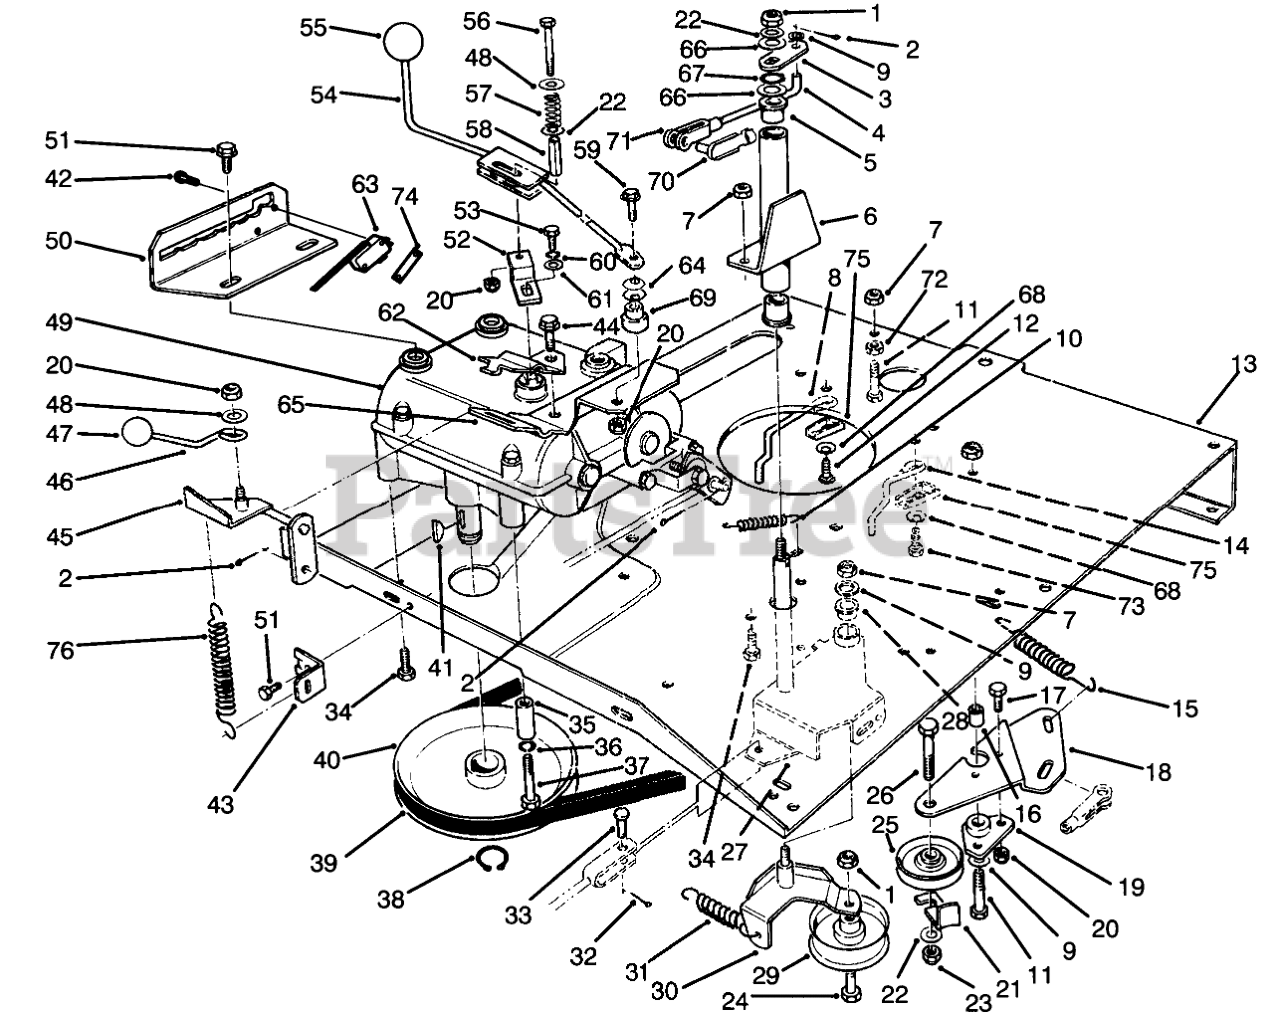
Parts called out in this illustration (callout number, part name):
1	NUT-LOCK, NI
2	PIN-COTTER
3	BRKT-DECK ENGAGE BLK
4	LINK-DECK ENGAGE
5	BUSHING-FLANGE
6	Tube W.A.-Pivot (Incl. Ref. #5)
7	NUT-LOCK, NI
8	ENG BELT GUIDE R.
9	WASHER-PLAIN
10	SPRING-RETURN, BRAKE
11	SCREW-HH
12	BOLT-CARR
13	PLATE-ENGINE
14	GUIDE-ENG. BELT L.
15	SPRING-TRACTION
16	SPACER-PIVOT
17	SCREW-HH
18	PLT-IDLER MTG
19	MOUNT-TRACTION PIVOT
20	NUT-LOCK, NI
21	RETAINER-BELT
22	WASHER-FLAT
23	NUT-LOCK, NI
24	SCREW-HH
25	PULLEY-IDLER
26	SCREW-HH
27	Bracket-Arm, Idler (Incl. Ref. #28)
28	BUSHING-FLANGE
29	PULLEY-IDLER
30	IDLER MTG PLT WA (BLACK)
31	SPRING-IDLER
32	SCREW-HSH
33	PIN-CLEVIS
34	SCREW-HH
35	GUIDE-BELT
36	WASHER-LOCK
37	SCREW-HH
38	RING-SNAP, EXTERNAL
39	67BELT, TRACTION DRIVE
40	PULLEY
41	KEY-WOODRUFF
42	SCREW-HH
43	BRKT-SPRING MT
44	SCREW-HWHTF
45	DECK ENGAGE LEVER WA (BLACK)
46	ROD-ENGAGE
47	KNOB-CONTROL
48	WASHER-FLAT
49	TRANSMISSION
50	Gate-Shift
51	SCREW-HWHTF
52	LEVER-SHIFT
53	SCREW-HH
54	SHIFT LEVER WA (BLACK)
56	SCREW-HH
57	SPRING-COMPRESSION
58	SPACER-SPLIT
59	SCREW-HH
60	WASHER-LOCK
61	WASHER-FLAT
62	BRKT-DECK ENG UPPER
63	SWITCH-MICRO
64	WASHER-BELLEVILLE
65	BRKT-DECK ENG. SHIFTER
66	WASHER
67	RING-RETAINING
68	WASHER-BELLEVILLE
69	SPACER-PIVOT
70	CLEVIS PIN ASM
71	CLEVIS-ADJ
72	NUT-JAM
73	SCREW-FLOW, TAPTITE
74	NUT-SPEED
75	ANCHOR-GUIDE, BELT
76	SPRING-DOOR
